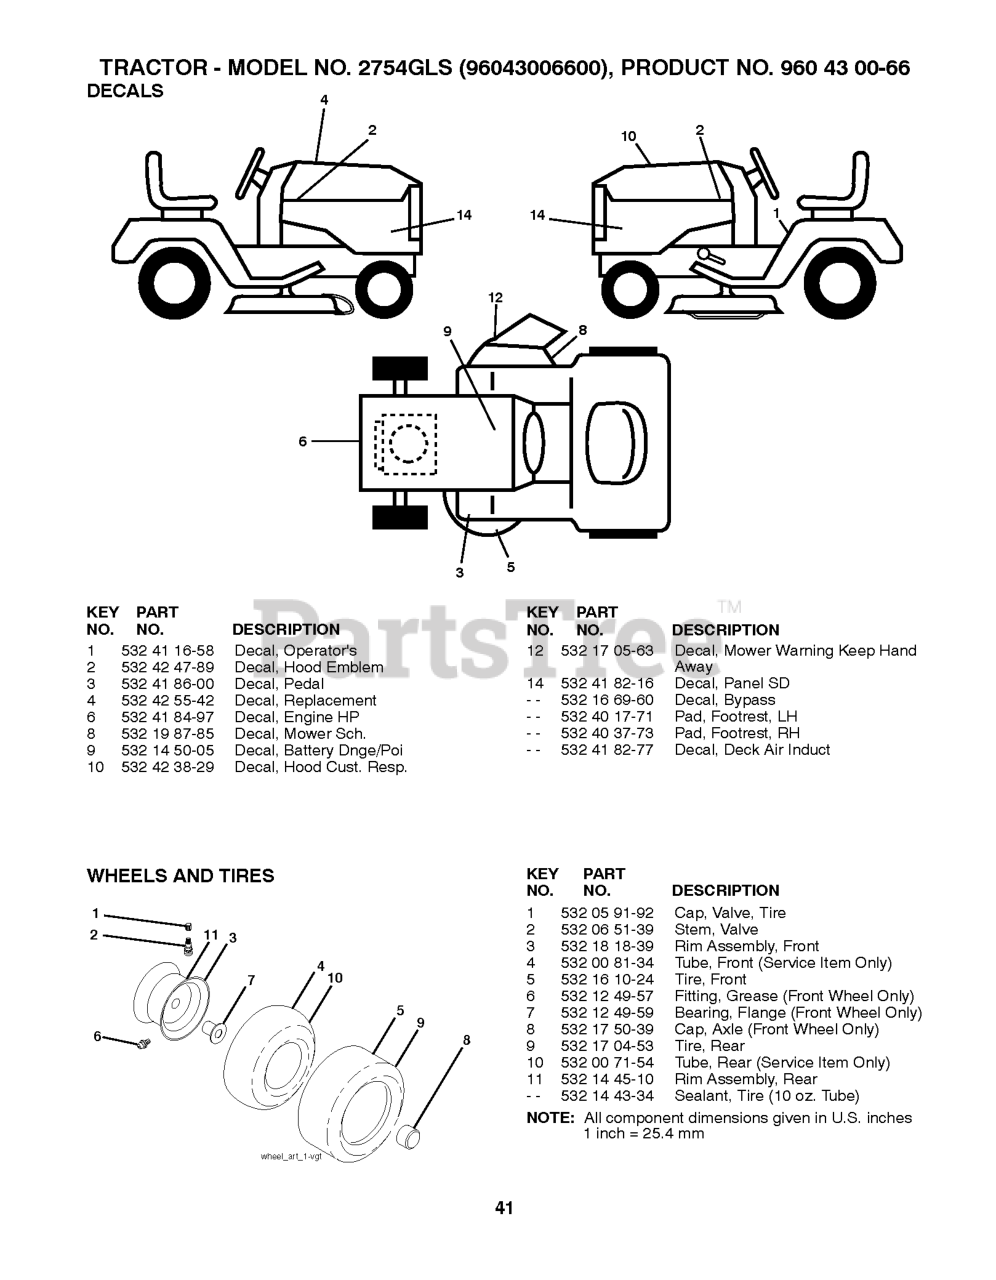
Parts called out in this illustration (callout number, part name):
2	VALVE STEM LT
3	RIM.ASM.8X5.FRONT.SILVER
4	TUBE.16X6.5/7.5-8
5	TIRE.16X6.5-8.TURF.MASTER
6	FITTING LT
7	BEARING T
8	CAP, AXLE BLK
9	TIRE.23X10.5-12.TURF.MASTER.RE
10	TUBE.23X9.5-12
11	RIM.ASM.12X7.REAR.SILVER
